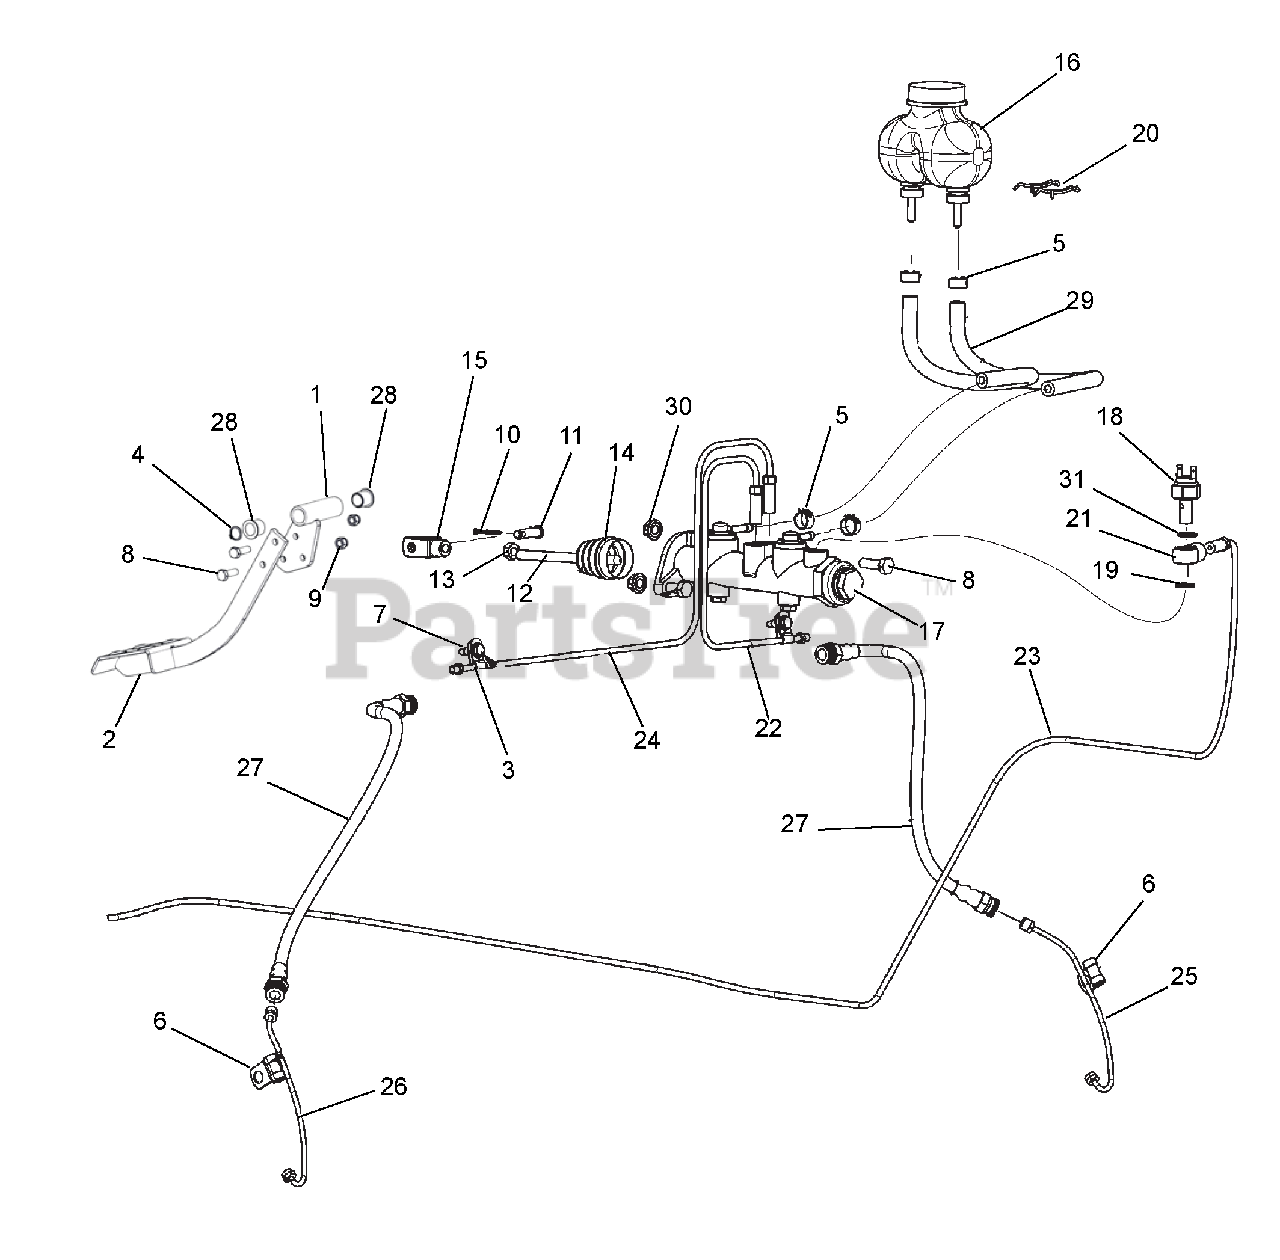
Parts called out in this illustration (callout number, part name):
1	BRAKE PEDAL PIVOT WELDMENT
2	BRAKE PEDAL ASM
3	WIRING/TUBE CLIP FOR 1/4 OD
4	SNAP RING, .625 X .035 EXT
5	CLAMP, FUEL LINE
6	HOSE CLAMP 1/4 ID
7	HH DRILL SCREW 1/4 X 3/4LG
8	@BLT-HEX .31-18X1.00 GR5 YWZC
9	@NUT-LK-NYL .312-18 YWZC
10	@PIN-CTR .09X1.00 EXTPRSQCT YZ
11	PIN-CLEV .313X1.00X.81 U
12	MASTER CYLINDER PUSH ROD
13	NUT, JAM M8-1.25 YWZC
14	MASTER CYLINDER BOOT
15	MASTER CYLINDER CLEVIS
16	DUAL RESERVOIR BRK FLUID W/CAP
17	DUAL MASTER CYLINDER
18	BRAKE SWITCH, HIGH PRESSURE
19	WASHER, COPPER, 3.5 MM
20	CLIP MASTER CYLINDER
21	BULK HEAD FLOW THROUGH
22	FRONT, BRAKE LINE LH
23	BRAKE, LINE MAIN
24	FRONT, BRAKE LINE RH
25	FRONT, BRAKE LINE END LH
26	FRONT, BRAKE LINE END RH
27	BRAKE LINE RBR 17" M10X1FEMALE
28	BUSHING 3/4ODX5/8IDX3/4 FLG HD
29	12.5" FUEL LINE/HYD FLUID RES.
30	@NUT-LK-TOP-FLG .31-18 YWZC
31	MSTR CYL CPPR WSHR 16X10X1.5MM
